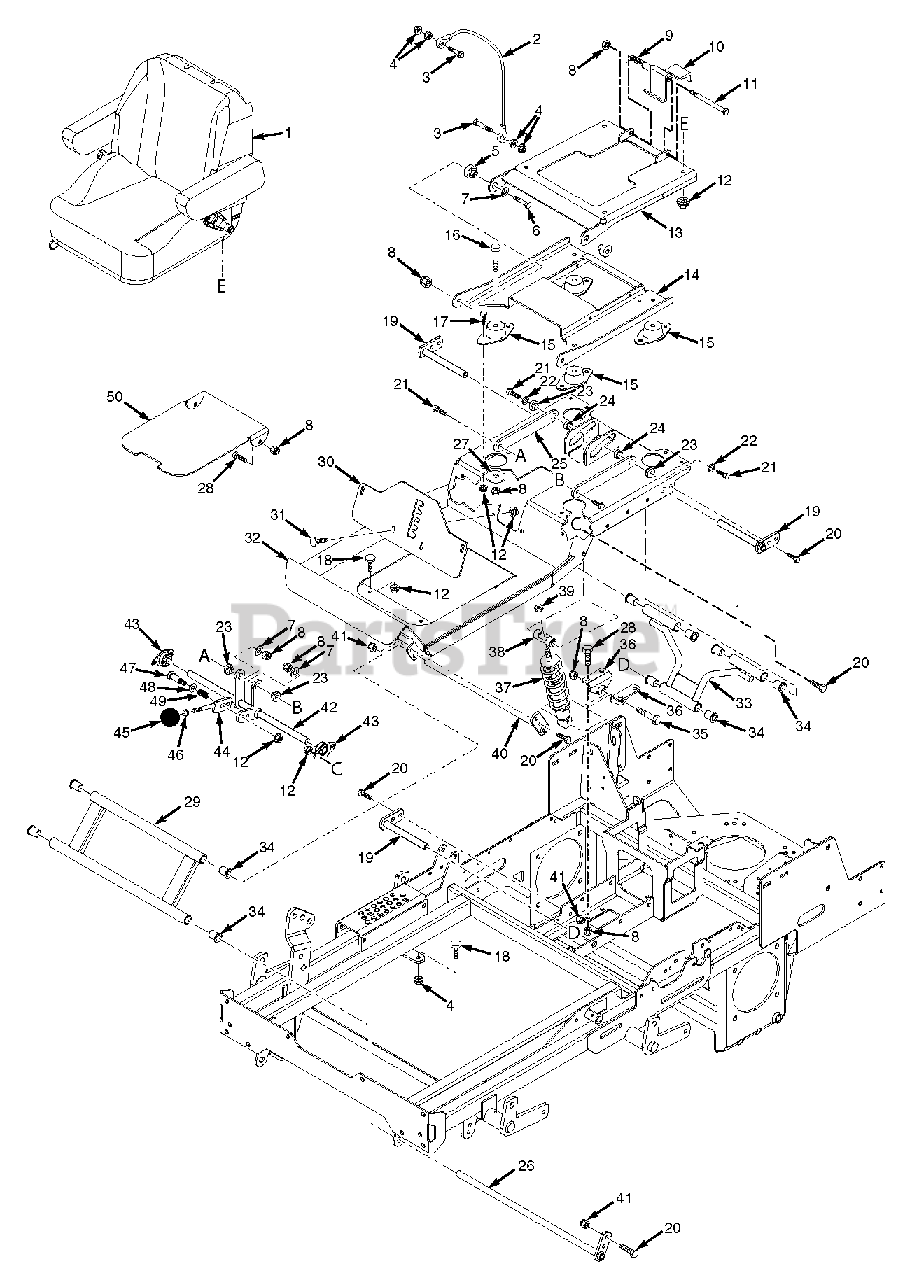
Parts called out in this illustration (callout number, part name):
1	Seat Assembly
2	Cable, Seat Stop
3	Bolt, Hex Head 1/4-20 x 1-1/4"
4	Nut, Serrated Flange 1/4-20
5	Sleeve, Seat Base Mount
6	Bolt, Hex Head 3/8-16 x 2"
7	Flatwasher, 3/8-.391 x .938 x .105
8	Nut, Elastic Stop 3/8-16
9	Spring, Seat Latch
10	Latch Weldment, Seat
11	Bolt, Hex Head 3/8-16 x 6"
12	Nut, Serrated Flange 5/16-18
13	Seat Plate Weldment
14	Seat Mounting Plate Weldment w/Decal
15	Isolator, Seat
16	Bolt, Hex Head 3/8-16 x 2-1/4"
17	Bolt, Hex Head 5/16-18 x 3/4"
18	Bumper, Rubber
19	Shaft Weldment, Rear Op. Platform Pivot
20	Bolt, Hex Head 5/16-18 x 1"
21	Bolt, Hex Head 3/8-16 x 1-1/2"
22	Lockwasher, 3/8" Spring
23	Bushing
24	Bearing
25	Link, Suspension Seat Tensioner
26	Pin Weldment, Op Platform Lower Pivot
27	Flatwasher, 3/8-.406 x 2.25 x .188
28	Bolt, Hex Head 3/8-16 x 1"
29	Suspension Pivot Assembly, Front
30	Bracket, Suspension Adjustment w/Decal
31	Bolt, Carriage 5/16-18 x 1"
32	Seat Mounting Base Weldment w/Decal
33	Suspension Pivot Assembly, Rear
34	Bearing
35	Bolt, Hex Head 3/8-16 x 2-3/4"
36	Mount Weldment, Shock
37	Shock Absorber, Suspension
38	Mount, Suspension Shock
39	Nut, Elastic Stop 3/8-24 Grade 8
40	Pin Weldment, Op Platform Upper Pivot
41	Nut, Elastic Stop 5/16-18
42	Pivot Weldment, Suspension Tensioner
43	Bearing, Self Align 5/8" ID
44	Adjustment Lever, Suspension
46	Nut, Jam 3/8-16
47	Bolt, Shoulder 3/8 x 1"
47	Bolt, Shoulder 3/8 x 3/8"
48	Flatwasher, 3/8-.406 x .812 x .065
49	Spring
50	Cover, Foot PLate
